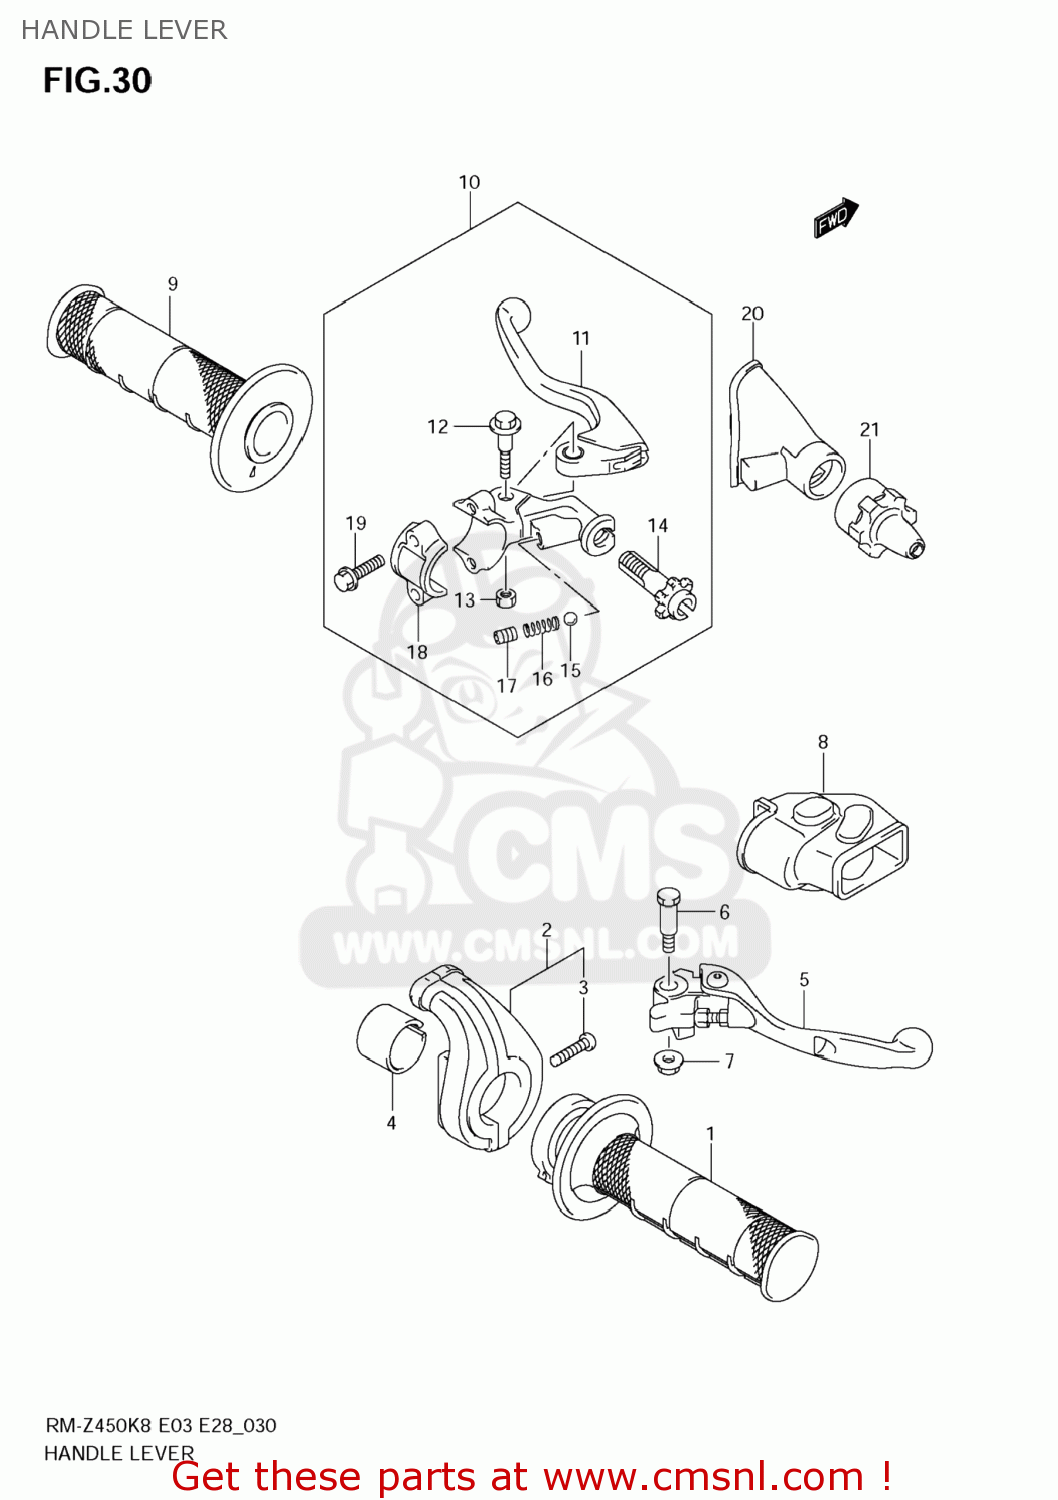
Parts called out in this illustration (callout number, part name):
1	GRIP,THROTTLE
2	CASE ASSY,THROTTLE
3	COLLAR,THROTTLE CASE
4	COVER,THROTTLE CASE
5	LEVER ASSY,BRAKE
6	BOLT,BRAKE LEVER
7	NUT
8	COVER,BRAKE LEVER
9	GRIP,L
10	LEVER ASSY,CLUTCH
11	LEVER,CLUTCH
12	BOLT
13	NUT
14	ADJUSTER,CLUTCH CABLE
15	BALL
16	SPRING
17	SCREW(6X8)
18	BRACKET,CLUTCH LEVER HOLDER
19	BOLT,BRACKET
20	COVER,CLUTCH LEVER
21	COVER,CLUTCH ADJUSTER
